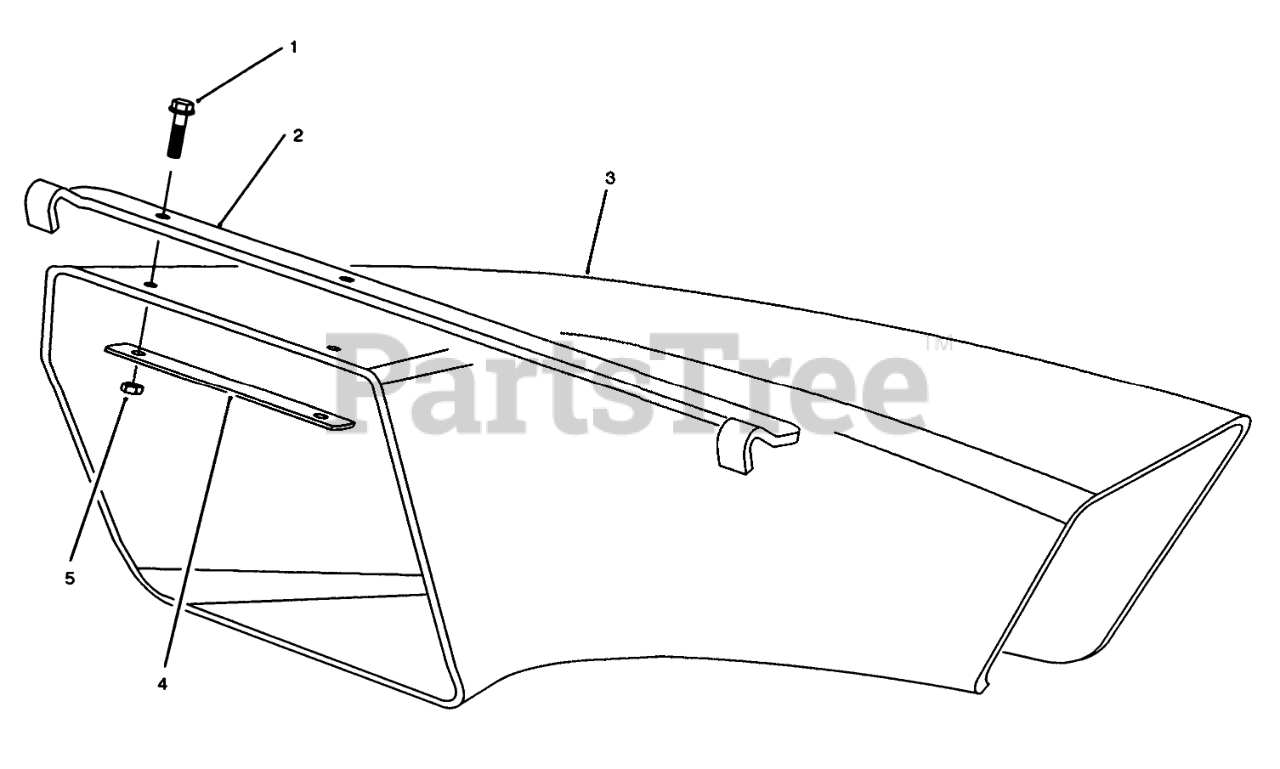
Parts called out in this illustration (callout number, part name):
1	SCREW-HWH
2	CHUTE HANGER BRACKET
3	Chute-Discharge
4	NUT-LOCK, NI
5	STRESS PLATE
